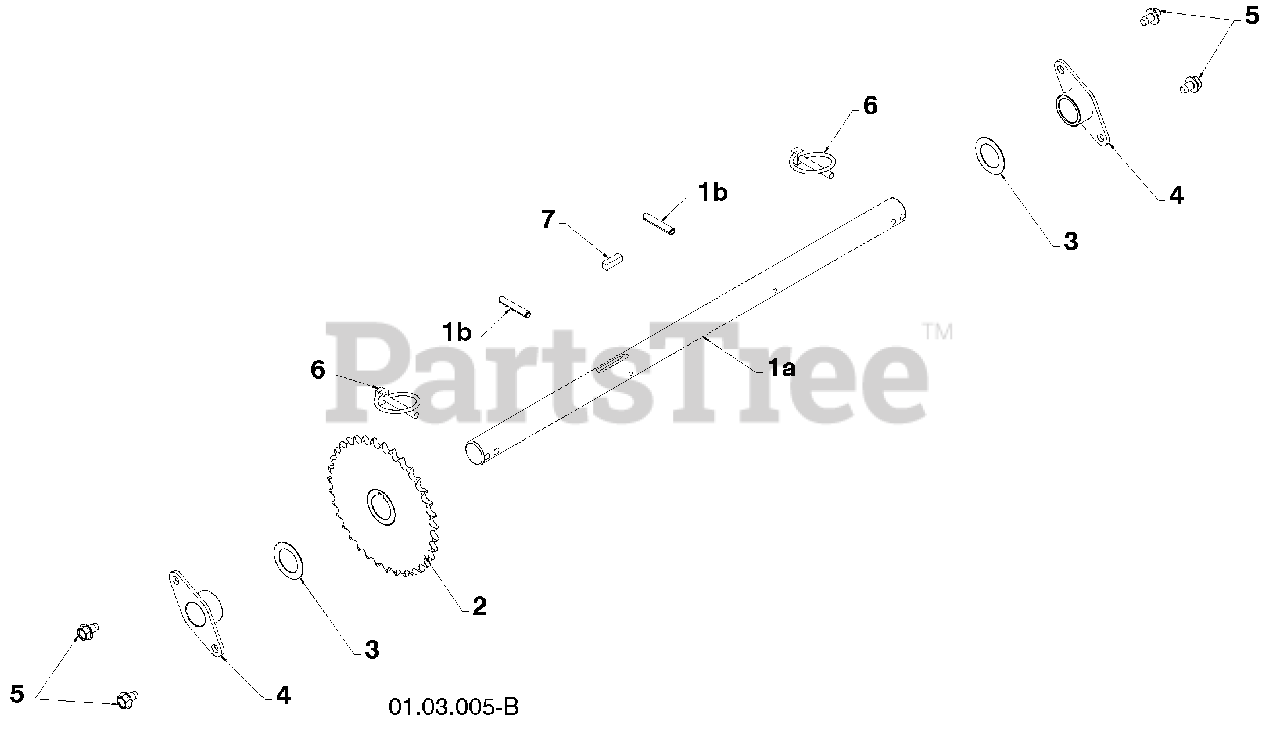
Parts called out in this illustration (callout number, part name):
1	(assy of 1a,1b) AXLE ASSEMBLY
2	SPROCKET
3	THRUST WASHER
4	BEARING
5	BOLT 5/16-18 X .500
6	CLIK PIN
7	SQUARE KEY
